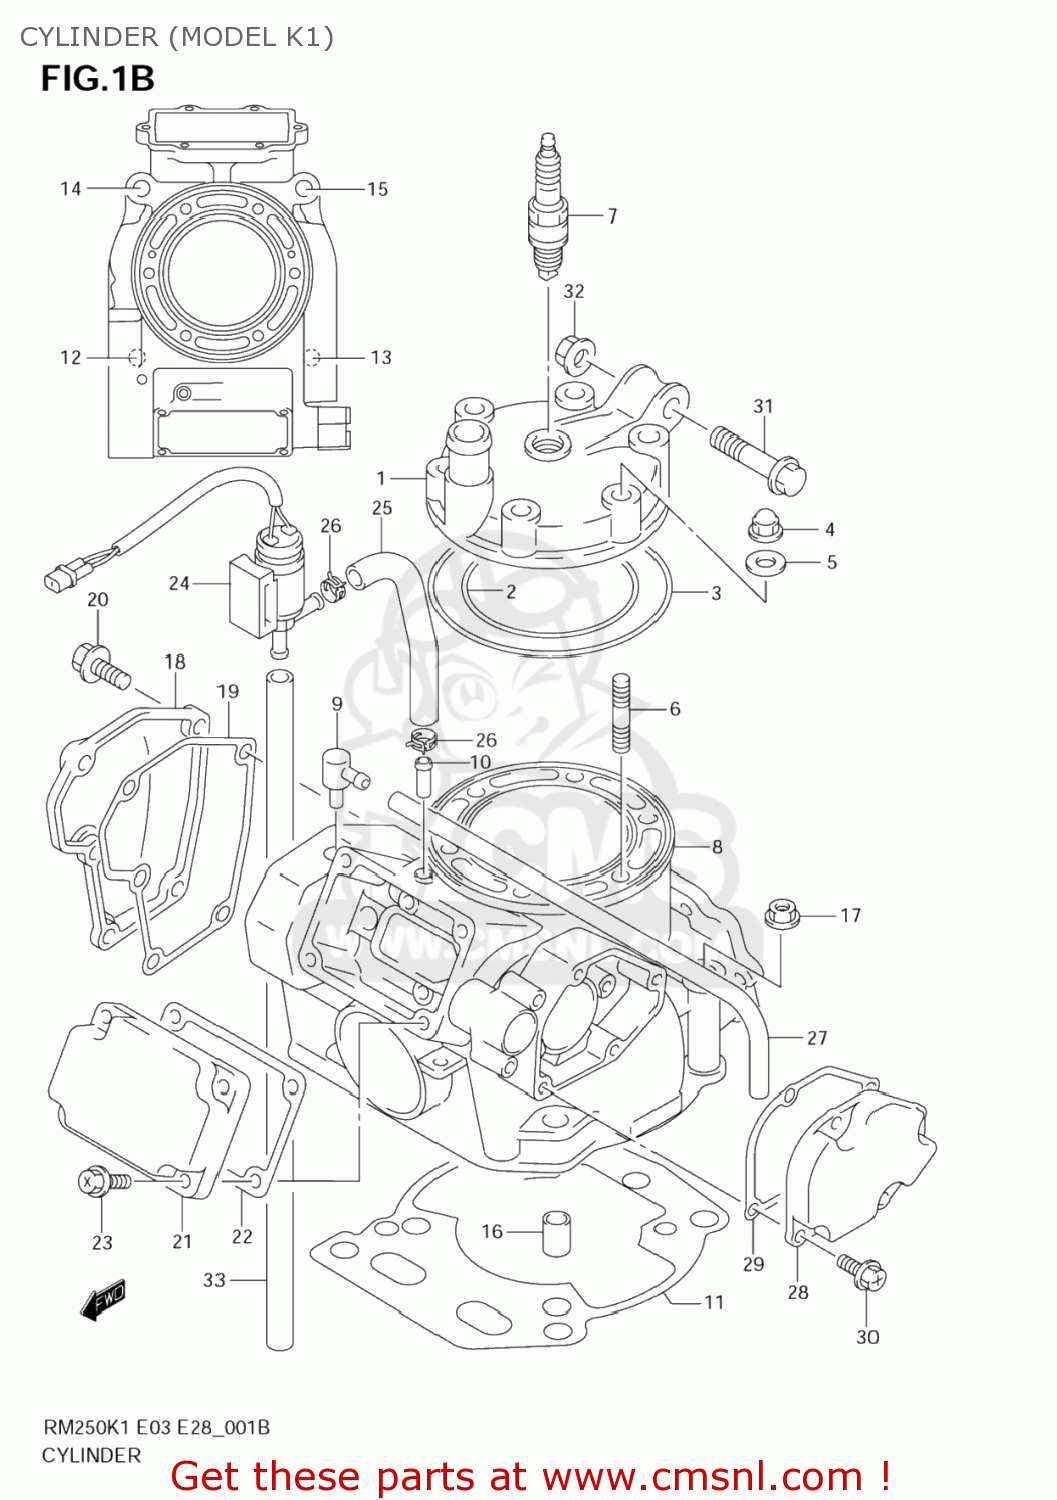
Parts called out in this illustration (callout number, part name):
1	HEAD,CYLINDER
2	O RING,CYLINDER HEAD NO.1
3	O RING,CYLINDER HEAD NO.2
4	NUT
5	GASKET(8.5X17X2.3) (NAS)
6	BOLT,STUD
7	PLUG,SPARK(BR8EG)
8	CYLINDER SET
9	UNION,BREATHER HOSE
10	UNION
11	GASKET,CYLINDER (NAS)
12	STUD 10X30
13	STUD BOLT (L:40)
14	STUD BOLT (L:60)
15	STUD BOLT (L:70)
16	PIN(13X10.4X20)
17	NUT
18	COVER,CYLINDER NO.1
19	GASKET,CYLINDER COVER NO.1 (NAS)
20	BOLT
21	COVER,CYLINDER NO.2
22	GASKET,CYL COVER NO.2
23	BOLT
24	SOLENOID VALVE ASSY
25	HOSE(6X10X600)
26	CLIP
27	HOSE(5X8.2X600)
28	COVER,CYLINDER NO.3
29	GASKET,CYL COVER NO.3 (NAS)
30	BOLT
31	BOLT(10X48)
32	NUT
33	HOSE(6X10X600)
